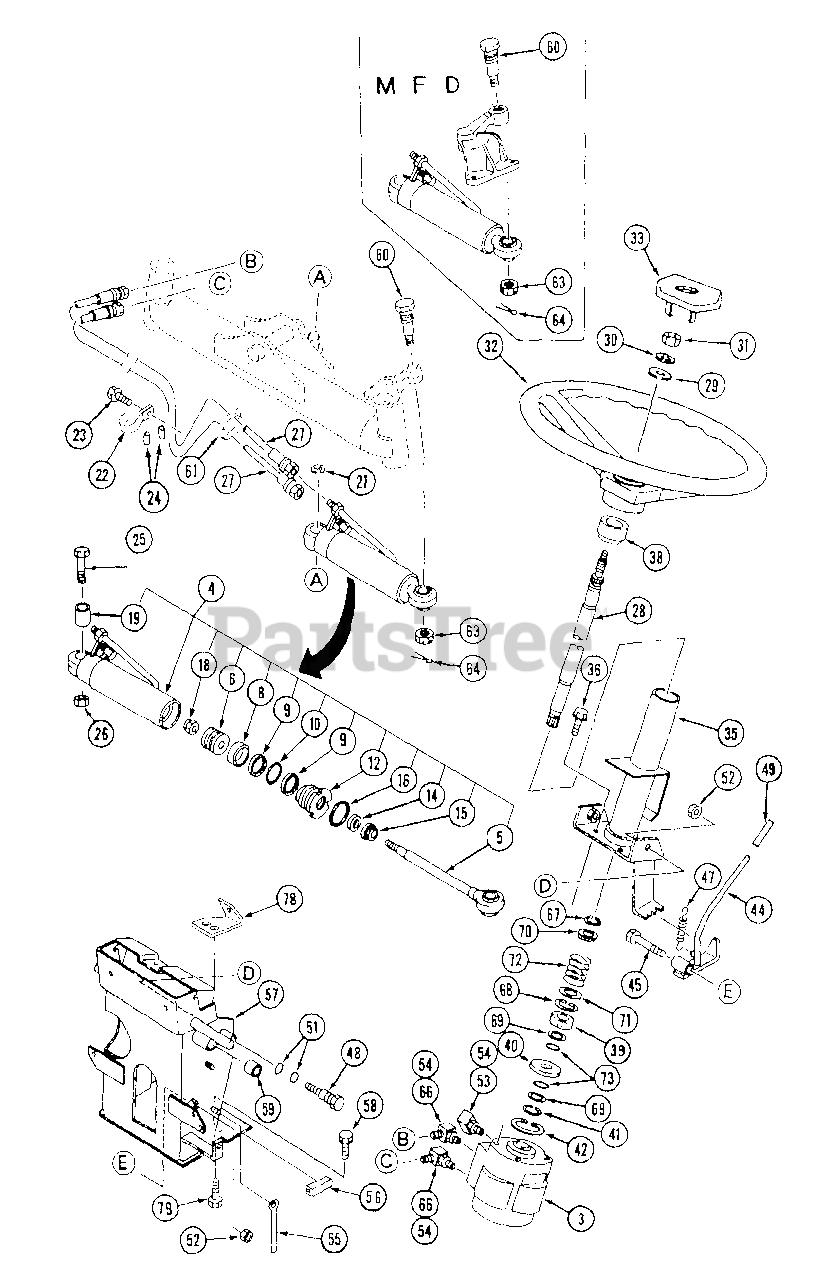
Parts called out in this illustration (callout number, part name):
3	Steering Unit
4	Cylinder Ass'y.
5	Rod, Cylinder
25	Bolt (MFD)
26	Nut (MFD)
28	Shaft, Steering
32	Steering Wheel
38	Bushing, Column
53	Valve, Check
57	Bracket, Column
66	Elbow 90
